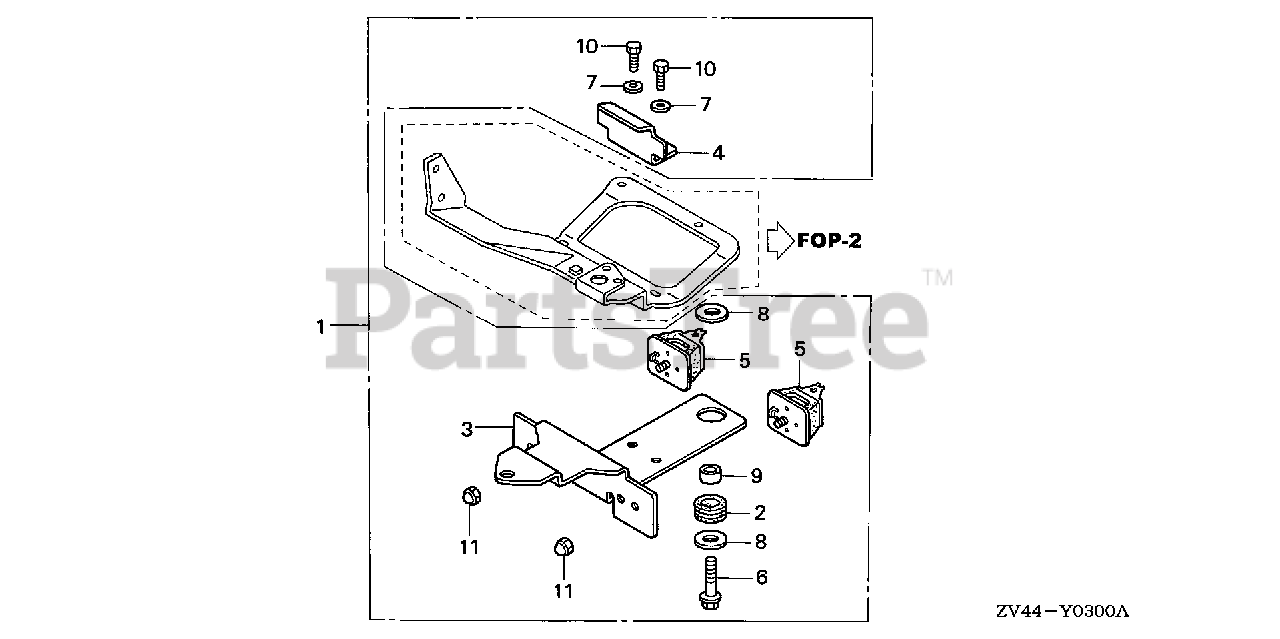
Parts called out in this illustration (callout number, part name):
1	BRACKET KIT, REMOTE CONTROL
2	RUBBER, BATTERY BOX SETTING
3	PLATE, STEERING
4	PLATE, BRACKET STOP
5	RUBBER, SETTING
6	BOLT, FLANGE (8X40)
7	WASHER, PLAIN (6MM)
8	WASHER, PLAIN (8MM)
9	COLLAR, STEERING
10	BOLT, HEX. (6X16)
11	NUT, CAP (6MM)
